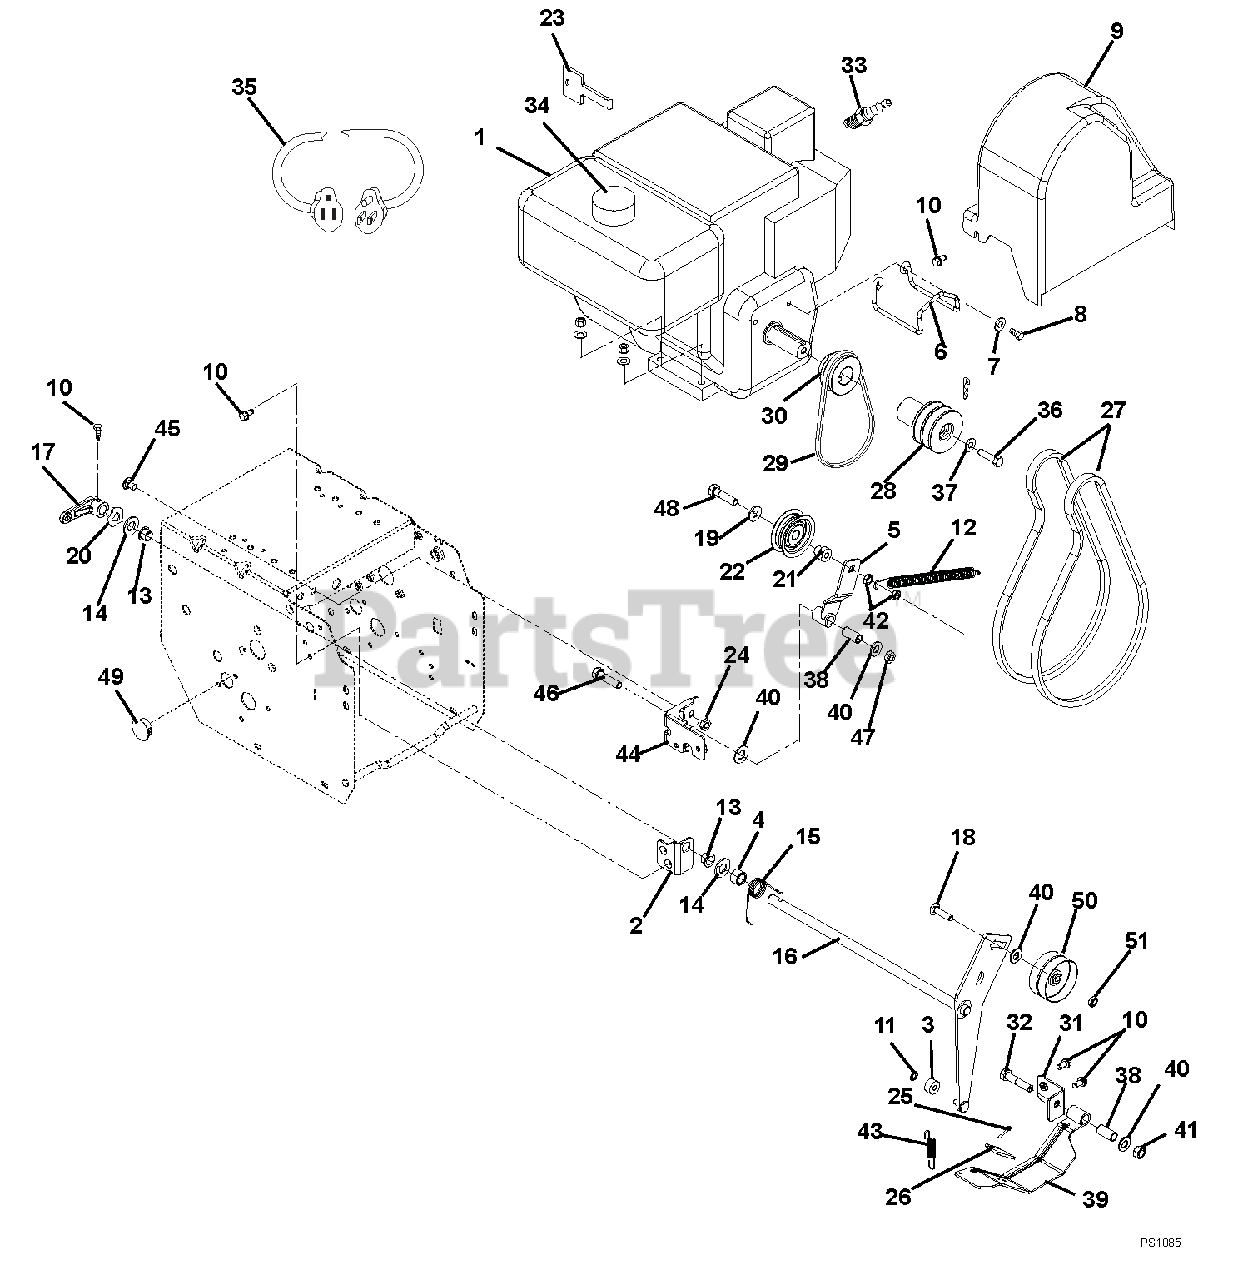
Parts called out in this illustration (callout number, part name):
1	ENGINE, 8HP TEC L-HD 120V
2	BRACKET, MOUNT - IDLER ARM
3	BSHG,SLV .270 X .750 X .250
4	BSHG-SLV .510X.751X.475
5	WELDMENT, TRACTION IDLER ARM
6	FINGER, BELT
7	WSHR-LK .312X.097 HVY YWZC
8	BLT-HEX .31-24X.75 YWZC GR5
9	PLZ SEE SERVICE LETTER #L-2166
10	@SCR-TAP .25-20X.50 HWH TR YWZ
11	RG-RTNG-EXT .250X.010
12	SPRING, SWIVEL HOOK EXTENSION
13	BUSHING, POLYLINER-.50 SPLIT
14	WSHR-FL-STL.531X1.00X.063 YWZC
15	SG-TORS .075 X .955
16	WELDMENT, ATTACHMENT IDLER ARM
17	ARM, CLUTCH - ATTACHMENT
18	@BLT-RHDSSQNK .38-16X1.75 G5YZ
19	@WSHR-FL-STL.38X.875X.083 YWZC
20	WSHR-WAVE .50X.75X.015 .13FRHT
21	SPCR, BRG .315X.50X.688X.281
22	IDLER
23	KEY, PUSH/PULL - TECUMSEH
24	@NUT-LK-TOP-FLG .31-18 YWZC
25	RVT-POP .187 YZ
26	PAD, BRAKE
27	V-BELT, HA-RAW EDGE (SET)
28	SHEAVE, ATTACHMENT 2 GROOVE
29	V-BELT, 3L-WRAPPED
30	SHEAVE, DRIVE
31	BRACKET, BRAKE MOUNT
32	@BLT-HEX .38-16X1.75 GR5 YWZC
33	PLUG, SPARK
34	CAP, FUEL - TECUMSEH
35	CORD, ELECTRIC START CORD 120V
36	BLT-HEX .38-24X2.25 YWZC GR5
37	@WSHR-LK .38X.094 REG YWZC
38	BSHG-SLV .385X.500X1.045
39	BRAKE ARM W/PAD
40	@WSHR-FL-STL.406X.812X.065 YWZ
41	@NUT-LK-CTR .38-16 YWZC
42	@NUT-LK-CTR-JAM .31-18 YWZC
43	SPRING-EXT .047 X .438 X 1.85
44	WELDMENT, FRAME BRACKET
45	@BLT-RHDSSQNK .31-18X.62 G5YZ
46	@BLT-HEX .38-16X1.50 GR5 YWZC
47	@NUT-LK-CTR-JAM .375-16 YWZC
48	@BLT-HEX .31-18X1.50 GR5 YWZC
49	PLUG, HOLE - .875" NYLON
50	IDLER-FLAT 2.75X.38 PAINTED
51	@NUT-LK-TOP-FLG .38-16 YWZC
